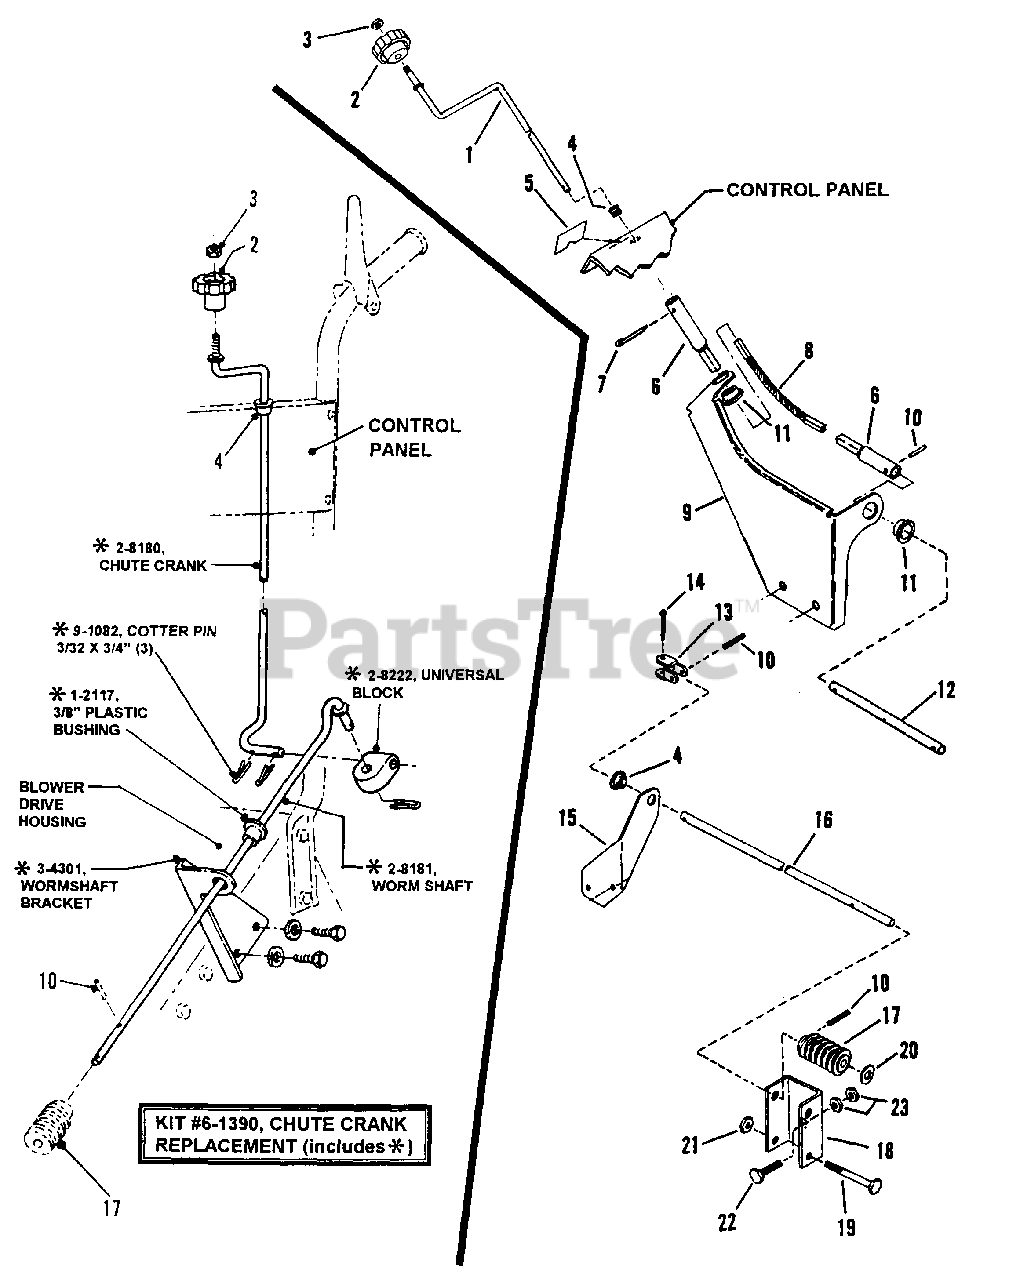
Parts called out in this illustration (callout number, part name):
1	CRANK, Chute (Series 0)
2	KNOB, Chute Crank
3	NUT, 5/16-18 Hex Center Lock
4	BUSHING
5	DECAL, Chute Control
6	FITTING, Core
7	PIN, 1/8 x 3/4" Cotter
8	SHAFT, Flexible
9	BRACKET, Flex Shaft
10	ROLL-PIN, 1/8 x 3/4"
11	BUSHING, 1/2"
12	SHAFT, Worm
13	CONNECTOR
14	COTTER-PIN, 1/8 x 1"
15	BRACKET, Worm Shaft Support
16	SHAFT, Worm
17	WORM
18	BRACKET, Worm Shaft
19	SCREW, 5/16-24 x 2-1/4" Hex Head Cap, Grade 5
20	WASHER, Spring Steel
21	NUT, 5/16-24 Hex Center Lock
22	BOLT, 5/16-18 x 1" Square Neck Carriage
23	NUT, 5/16-18 Hex
